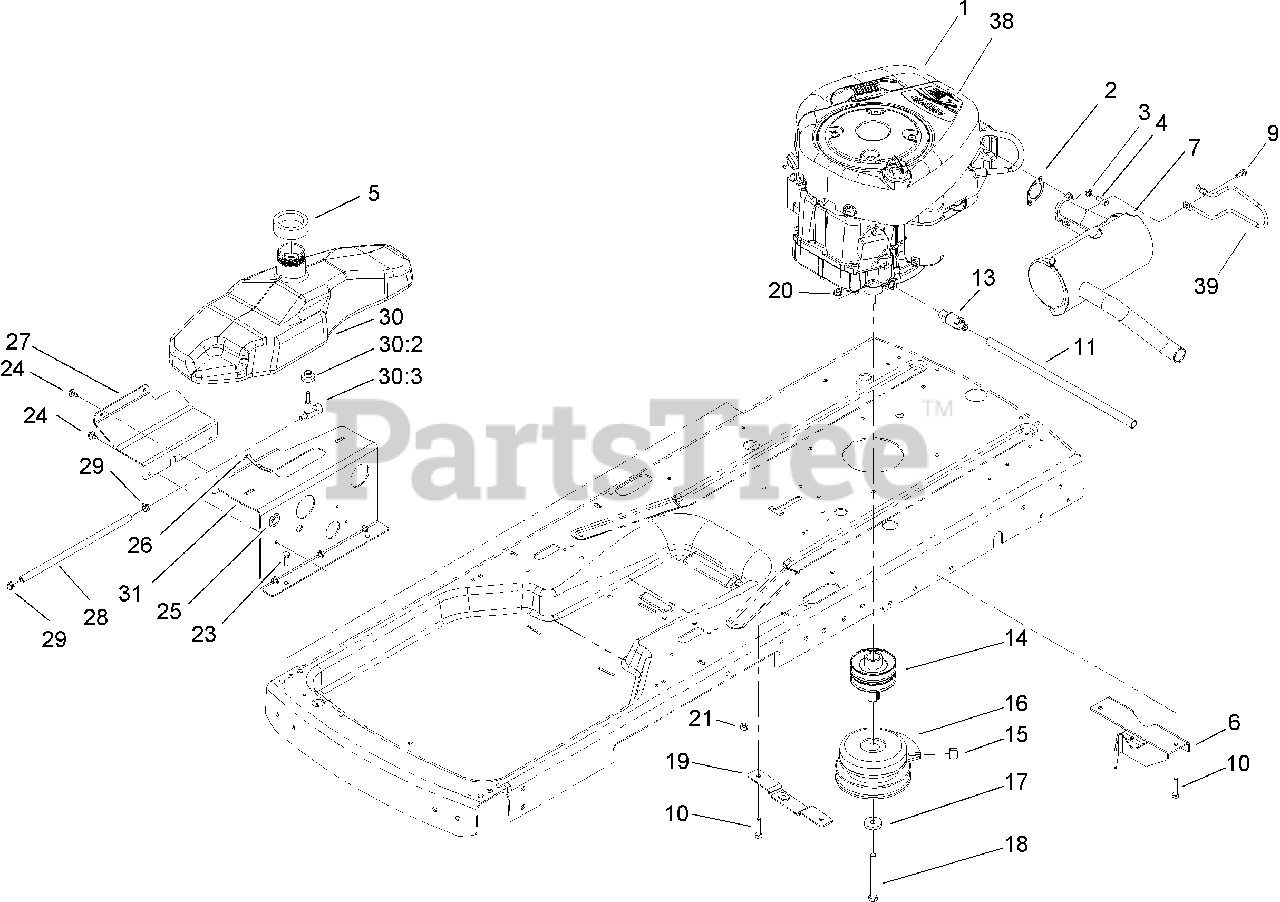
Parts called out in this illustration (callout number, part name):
2	GASKET-MUFFLER
3	WASHER-LOCK
4	SCREW-HSH
5	SEAL-FOAM
6	BRACKET-PIVOT
9	SCREW-HWH
10	SCREW-HH
11	TUBE-DRAIN, OIL
13	VALVE-DRAIN, OIL
14	PULLEY-ENGINE
16	CLUTCH-ELECTRIC
18	SCREW-HH
19	PLATE-MOUNT, IDLER
21	NUT-LOCK, NI
23	SCREW-HH
24	SCREW-HHF
27	PLATE-SUPPORT
28	HOSE-FUEL
30	FUEL TANK ASM
30:3	VALVE-FUEL
38	DECAL-ENGINE
39	GUARD-MUFFLER
